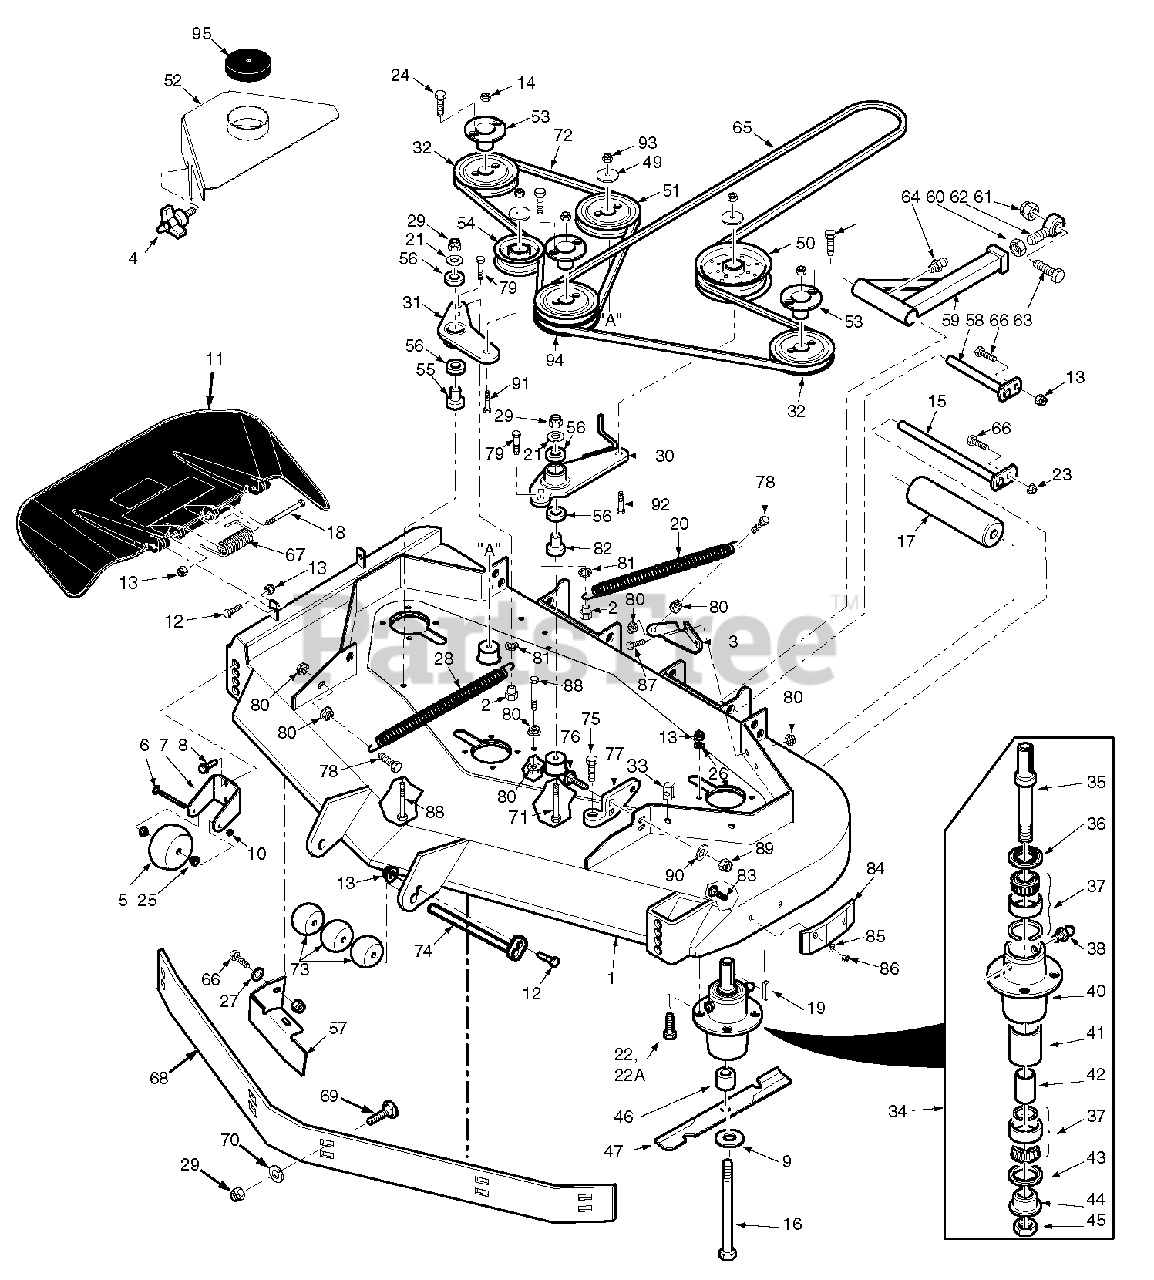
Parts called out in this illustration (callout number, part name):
1	Cutter Deck Velocity Plus
2	Boss, Spring Anchor
3	Bracket, LH Spring Anchor 61V
4	Wing Nut, 3/8-16
5	Anti-Scalp Wheel
6	Bolt, Carriage 3/8-16 x 4"
7	Bracket, Anti-Scalp Wheel
8	Bolt, Serrated Flange 3/8-16 x 1"
9	Flatwasher, 5/8" Hardened
10	Locknut, 3/8-16 Center Lock
11	Discharge Chute Assy.
12	Bolt, Hex Head 5/16-18 x 1-1/2", Rear
12	Bolt, Hex Head 5/16-18 x 1-3/4", Front
13	Nut, Elastic Stop 5/16-18
14	Nut, 5/8-11 UNC
15	Shaft, Roller
16	Bolt, Hex Head 5/8-11 x 9-1/2"
17	Roller, Rear
18	Bolt, Hex Head 5/16-18 x 4-3/4"
19	Key, 1/4 x 1/4 x 2"
20	Spring, LH Deck Drive
21	Flatwasher, 3/8" - .938 x .391 x .105"
22	Bolt, Hex Head 5/16-18 x 1-3/4"
23	Nut, Serrated Flange 5/16-18
24	Bolt, Hex Head 1/4-20 x 1"
25	Bushing, .376 ID Oilite
26	Lockwasher 5/16"
27	Flatwasher 5/16"
28	Spring, RH Deck Drive
29	Nut, Elastic Stop 3/8-16
30	Idler Arm Assembly, LH Drive
31	lder Arm Assembly, RH Drive
32	Pulley, Tapered Bore 6.33" Dia.
33	U-Nut, 3/8-16
34	Spindle Assembly
35	Shaft, Spindle
36	Seal Upper
37	Bearing Assembly
38	Grease Fitting
39	Valve, Grease Relief
40	Housing, Spindle
41	Spacer, Outside
42	Spacer, Inside
43	Seal, Lower
44	Bushing, Bottom
45	Nut, Special 1-1/16 - 18
46	Spacer, Spindle
47	Cutter Blade 21"
48	Pulley, Double Groove 6.33" Dia.
49	Dust Shield
50	Idler Pulley, 5" Dia.
51	Idler Pulley, 5" Dia.
52	Belt Cover (61V)
53	Hub, Tapered 1-1/8" Bore
54	Idler Pulley, 3-1/2" Dia.
55	Pivot, Idler
56	Bearing
57	Turbo Baffle, Bolt On
58	Push Arm Shaft
59	Push Arm (Includes 64,60,62)
60	Nut, 5/8-18 UNF
61	Nut, Elastic Stop 5/8-11
62	Rod End, 5/8 Male RH Thread
63	Bolt, Hex Head 5/8-11 x 4-1/2"
64	Grease Fitting, 90 Degree
65	Belt, Deck Drive 61V
66	Bolt, Hex Head 5/16-18 x 1"
67	Spring, Discharge Chute
68	Baffle Custom-Cut, 61V (7-Position)
69	Bolt, Carriage 3/8-16 x 1"
70	Flatwasher, 3/8-.391 x .938 x .105"
71	Bolt, Hex Head 3/8-16 X 3-1/2"
72	Belt, Deck Drive RH
73	Wheel, Anti Scalp
74	Roller Shaft
75	Bolt, Special
76	Bolt, Carriage 7/16-14 x 1-1/4"
77	Lever Assy., Deck Level
78	Bolt, Hex Head 3/8-16 x 1-1/2" Gr.8
79	Bolt, Hex Head 3/8-16 x 1"
80	Nut, Serrated Flange 3/8-16
81	Lockwasher, 5/16"
82	Pivot, Idler Short
83	Bolt, Carr. 5/16-18 x 3/4"
84	Wear Pad
85	Flatwasher, 5/16-.344 x .688 x .065"
86	Nut, Center Lock 5/16"
87	Bolt, Hex Head 3/8-16 x 1"
88	Bolt, Hex Head 3/8-16 x 2-1/2"
89	Nut, Elastic Stop 7/16-14
90	Flatwasher, 7/16-.500 x 1.250 x .083"
91	Bolt, Hex Head 3/8-16 x 2-1/4"
92	Bolt, Hex Head 3/8-16 x 3"
93	Nut, Elastic Stop 3/8-16
94	Pulley, Double Groove 6.33" Dia.
95	Cap, Spindle
